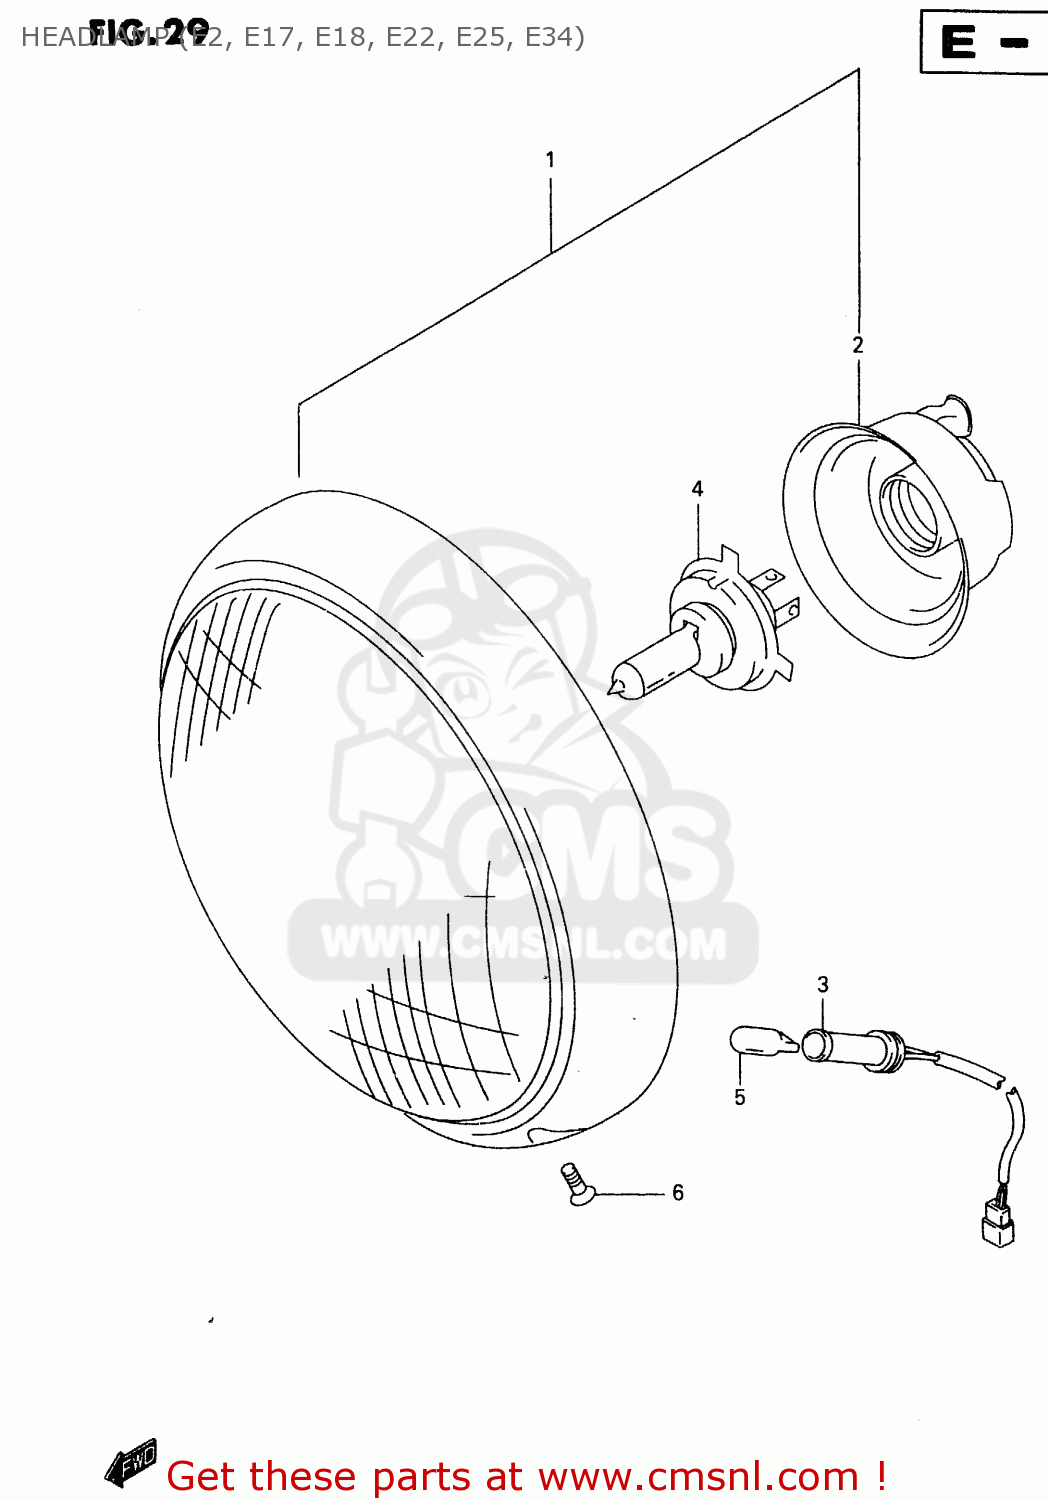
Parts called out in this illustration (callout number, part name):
1	HEADLAMP ASSY
2	COVER,SOCKET
3	CORD ASSY
4	BULB(12V60/55W,H4)
5	BULB(12V4W)
6	SCREW(5X12)
